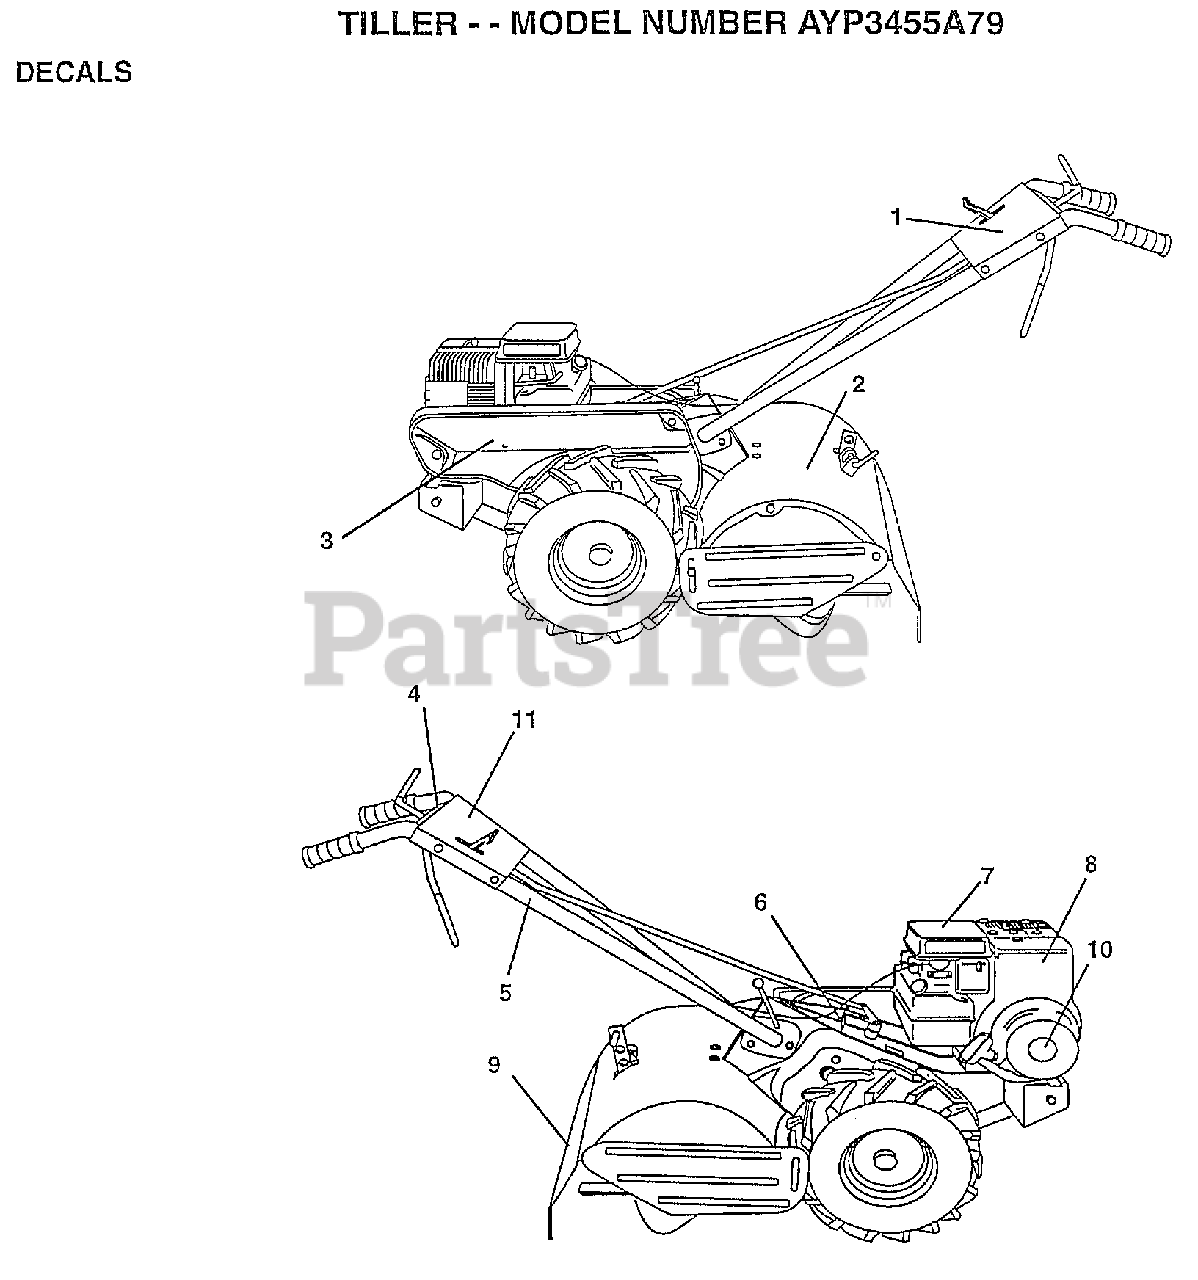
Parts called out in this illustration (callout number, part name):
1	DECAL, LOGO
3	DECAL.GUARD.BLT.W
5	DECAL TI
6	DECAL CRT
8	DECAL, BRIGGS & STRATTON
9	DECAL TI
10	DECAL, 5.5 HP
11	DECAL REVERSE
